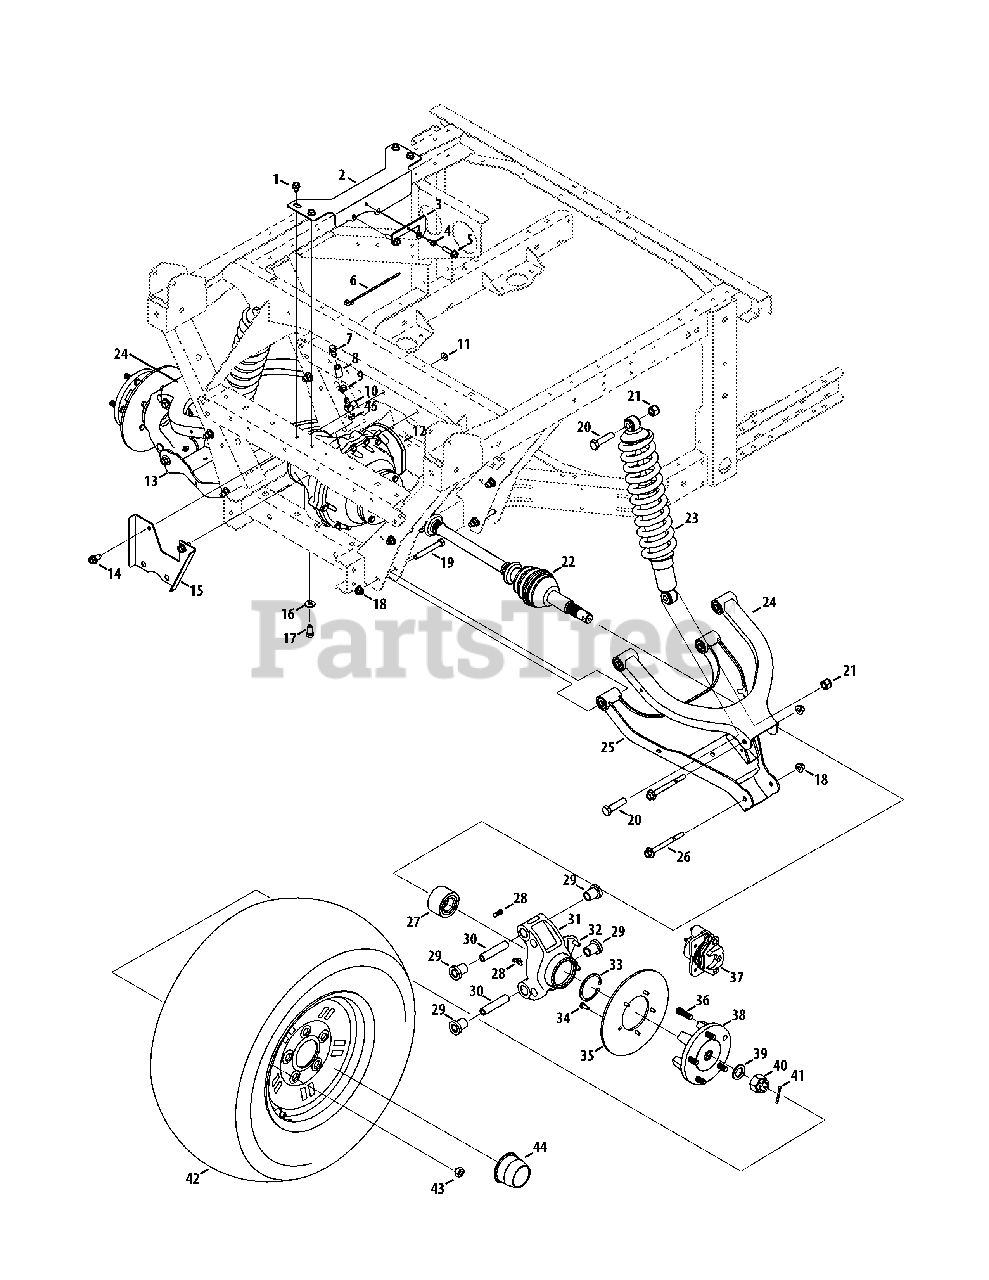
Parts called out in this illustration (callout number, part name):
1	Screw, tt, 5/16-18 x 0.500
2	Bracket, rear/diff, 4x4
3	Spacer, Differential
4	Screw, tt, 1/4-20 x .500
5	Screw, m8-1.25, 30.00
6	Tie, Cable
7	Vent, 3/8 Dia.
8	Hose, fuel Line
9	Clamp, hose, .490 Dia.
10	Fitting, Fuel Pickup
11	Washer, Flat, .344 x .688 x .065
12	Differential Assembly, complete
13	Control Assembly, lwr, l/rr
14	Screw, tt, 3/8-16 x .750
15	Bracket, Diff, rr
16	Washer, Flat, .385 x .870 x .092
17	Screw, 3/8-16 x .75, gr5, std
18	Nut, Flange Lock, 3/8-16, Nylon
19	Screw, 3/8-16 x 3.00, gr8, std
20	Screw, 1/2-13 x 2.00, gr5, std
21	Nut, Hex Lock, 1/2-13, Nylon
22	Axle Assembly, cv Joint
23	Shabs, 5.0 Stroke, rr
24	Control Assembly, rr Upr
25	Control Assembly, lwr, r/rr
26	Screw, 3/8-16 x 4.00, gr5
27	Bearing, dble Row, 60x30x37
28	Fitting, Grease
29	Bearing, Flange, .625 x .750 x .750
30	Tube, pivot, rr/cont Arm
31	Housing, rr, mach
32	Screw, m8-1.25, 25.00
33	Ring, retainer, dho-60
34	Screw, 1/4-20 x .625, gr5, lock
35	Disc, brake, 8.00x.188
36	Stud, rib Neck, 7/16-14 x 1.6
37	Brake, hydraulic, caliper, frt, RH
38	Hub, wheel
39	Washer, flat, .88 x 1.38 x .125, ht
40	Nut, slotted, 22x1.5
41	Pin, cotter, 5/32, 1.25
42	Wheel Assembly, RH, 25 x 11-12
42	Wheel Assembly, RH,25 x 11-12, black
42	Wheel Assembly, RH, 26 x 11-12
42	Wheel Assembly, LH, 25 x 11-12
42	Wheel Assembly, LH, 25 x 11-12, black
42	Wheel Assembly, LH, 26 x 11-12
42	Wheel Assembly, compl, 25x10-12
43	Nut, lug, 7/16-14
43	Nut, lug, 7/16-14, Chrome
44	Cap, Wheel UV
44	Cap, Wheel UV, Chrome
45	Nut, Jam, M12 x 1.5 x 6MM
